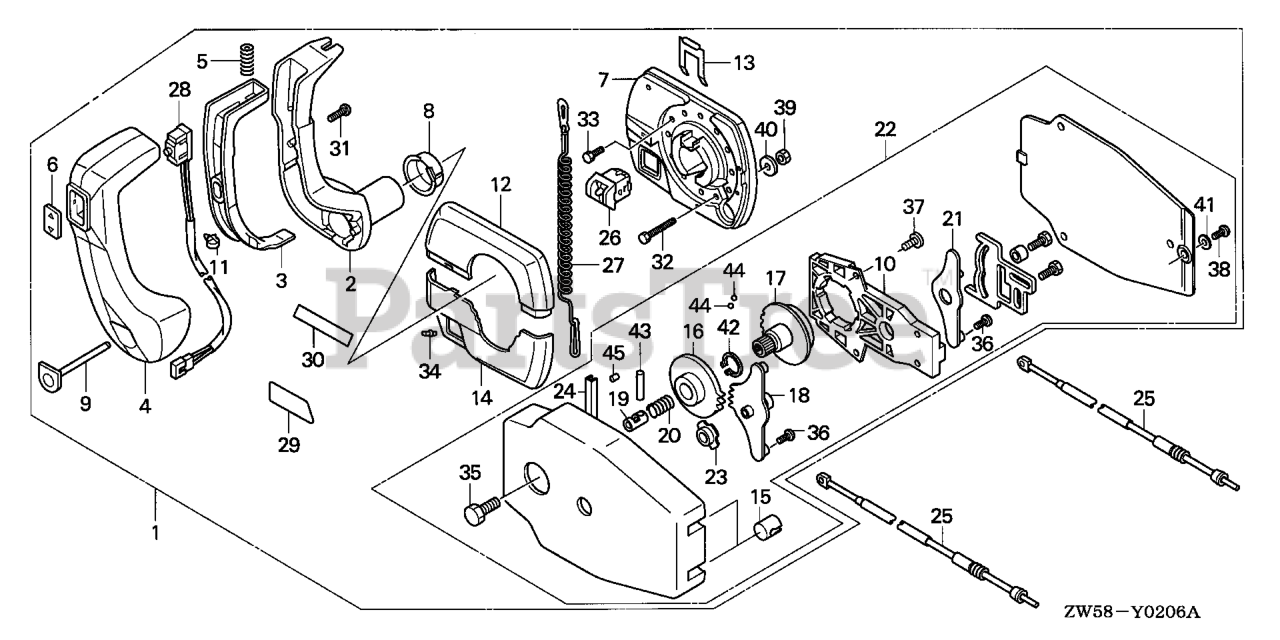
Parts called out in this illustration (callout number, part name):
1	BOX ASSY., REMOTE CONTROL (PANEL MOUNT) (NA USE ALT:06240-ZW7-U00)
2	HANDLE, REMOTE CONTROL
3	LEVER, HANDLE LOCK
4	GRIP, REMOTE CONTROL HANDLE
5	SPRING, REMOTE CONTROL HANDLE
6	COVER, GRIP
7	HOUSING ASSY., REMOTE CONTROL BOX (A)
8	BUSHING Use up to Frame SN 4000953.
9	BUTTON, THROTTLE
10	FRAME ASSY., REMOTE CONTROL BOX
11	BAND B, CABLE Use up to Frame SN 4000953.
12	HOUSING ASSY., REMOTE CONTROL BOX (B)
13	RETAINER
14	HOUSING, REMOTE CONTROL BOX (C)
15	GROMMET
16	WHEEL, CONTROL
17	SHAFT, HANDLE (N/A: SEE ASSEMBLY) (NOT AVAILABLE)
18	ARM ASSY., SHIFT LINK
19	SHAFT, GEARSHIFT
20	SPRING, GEARSHIFT
21	ARM ASSY., THROTTLE LINK
22	HOUSING ASSY. (INNER) (PANEL MOUNT)
23	BUSH
24	SPRING
25	CABLE, REMOTE CONTROL (10') (NOT AVAILABLE)
25	CABLE, REMOTE CONTROL (1 1'') (BRUNSWICK) (NOT AVAILABLE)
25	CABLE, REMOTE CONTROL (1 2'') (BRUNSWICK) (NOT AVAILABLE)
25	CABLE, REMOTE CONTROL (1 3'') (BRUNSWICK) (NOT AVAILABLE)
25	CABLE, REMOTE CONTROL (1 4'') (BRUNSWICK) (NOT AVAILABLE)
25	CABLE, REMOTE CONTROL (1 5'') (BRUNSWICK) (NOT AVAILABLE)
25	CABLE, REMOTE CONTROL (1 6'') (BRUNSWICK) (NOT AVAILABLE)
25	CABLE, REMOTE CONTROL (1 7'') (BRUNSWICK) (NOT AVAILABLE)
25	CABLE, REMOTE CONTROL (1 8'') (BRUNSWICK) (NOT AVAILABLE)
25	CABLE, REMOTE CONTROL (1 9'') (BRUNSWICK) (NOT AVAILABLE)
25	CABLE, REMOTE CONTROL (2 0') (BRUNSWICK) (NOT AVAILABLE) (ALT. PNO: 24920-ZW1-003AH)
26	SWITCH ASSY., EMERGENCY STOP
27	WIRE, EMERGENCY
28	SWITCH ASSY., POWER TRIM-TILT (A) Use up to Frame SN 4000953.
29	MARK, REMOTE CONTROL (A)(PANEL)
30	MARK, REMOTE CONTROL (B)(FOR STARBOARD)
30	MARK, REMOTE CONTROL (C)(FOR PORT)
31	SCREW A (NOT AVAILABLE)
32	SCREW B
33	SCREW C
34	SCREW SET (1/4-20X16") Use up to Frame SN 4000953.
35	BOLT
36	SCREW (8-32X3/8)
37	SCREW (10-32X5/8)
38	SCREW (10-32X5/8)
39	NUT (1/4X20)
40	WASHER
41	WASHER Use up to Frame SN 4000953.
42	CIRCLIP (OUTER)
43	PIN, GEARSHIFT
44	BALL, STEEL
45	ROLLER, SHIFT CLICK
